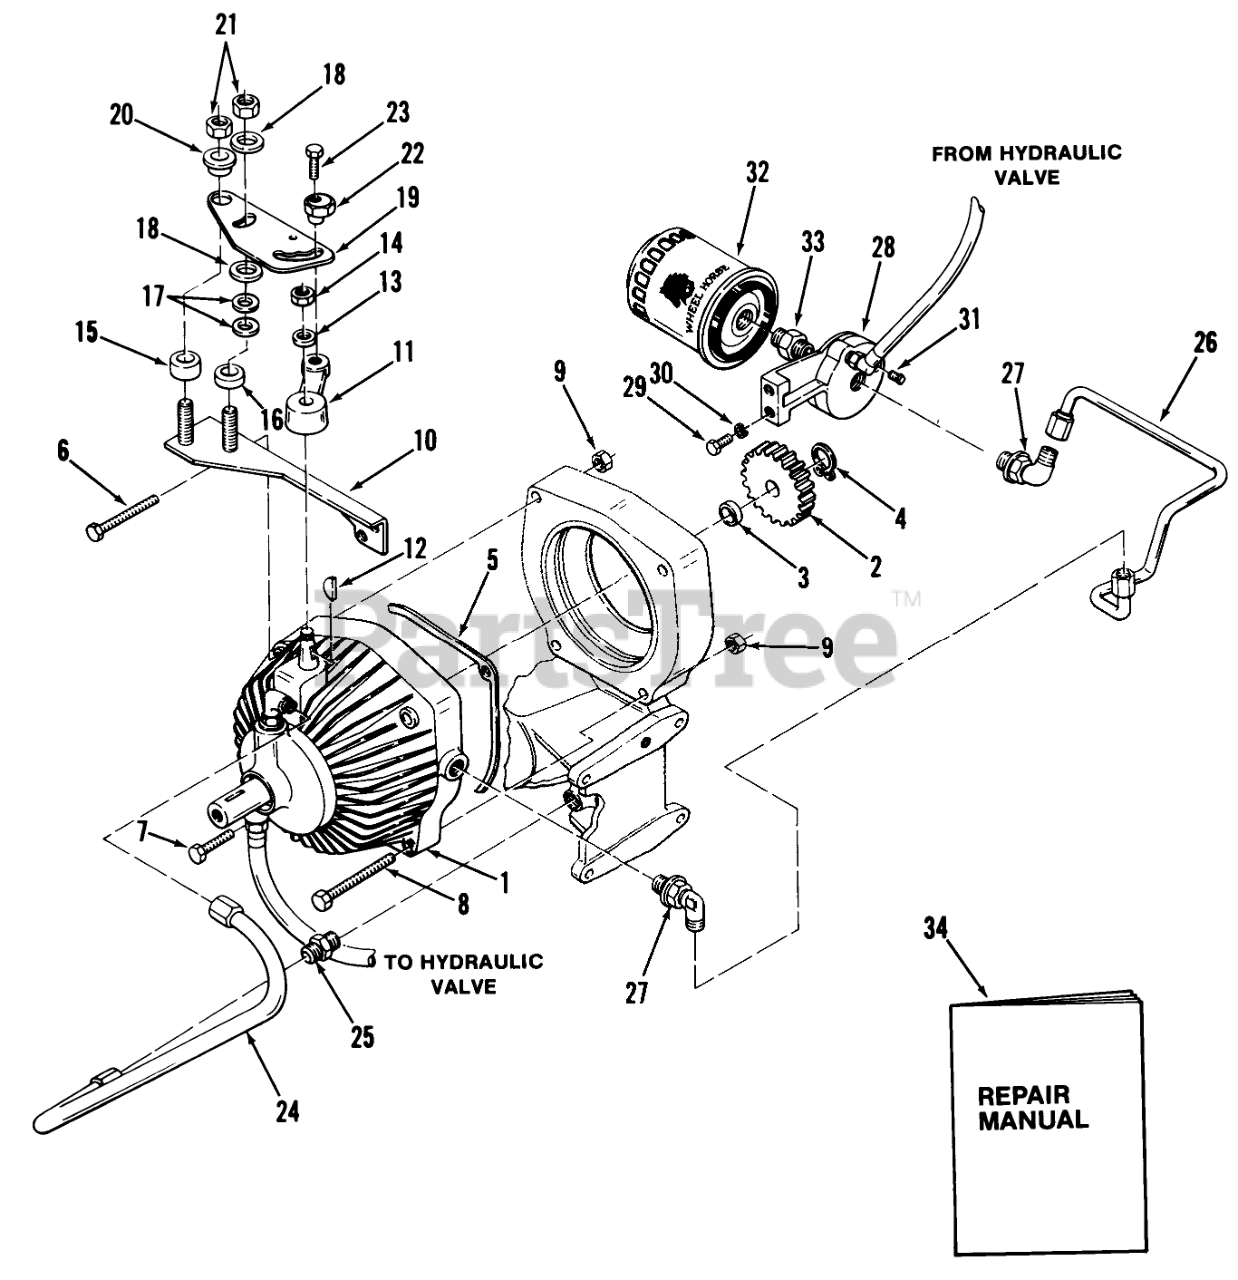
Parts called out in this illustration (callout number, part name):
1	Pump & Motor
2	GEAR 22T DRIVE
3	SPACER GEAR
4	SNAP RING- 5/8 EXT
5	GASKET
6	H H C S
7	Bolt
8	Bolt 3/8-16 x 6 1/2
9	Nut
10	ASSY-PLATE B
11	ARM-SPEED CONTROLB
12	Key #5 Woodruff
13	Washer
14	Eslok Nut
15	SPACER-PIVOT
16	SPACER-FRICTION
17	WASHER-SPRING DISC
18	FRICTION WASHER
19	CAM-SPEED CONTROL (NS)
20	CAM-SPACER
23	Bolt
24	ASSY-TUBE-SUCTION
25	FITTING-TUBE
26	ASM-TUBE FILTER OUTL
27	ELBOW
28	BASE-FILTER
29	Bolt
30	Lockwasher
31	PLUG 1/4 PIPE ALLEN
32	Filter-Oil
33	FITTING
34	Repair Manual
